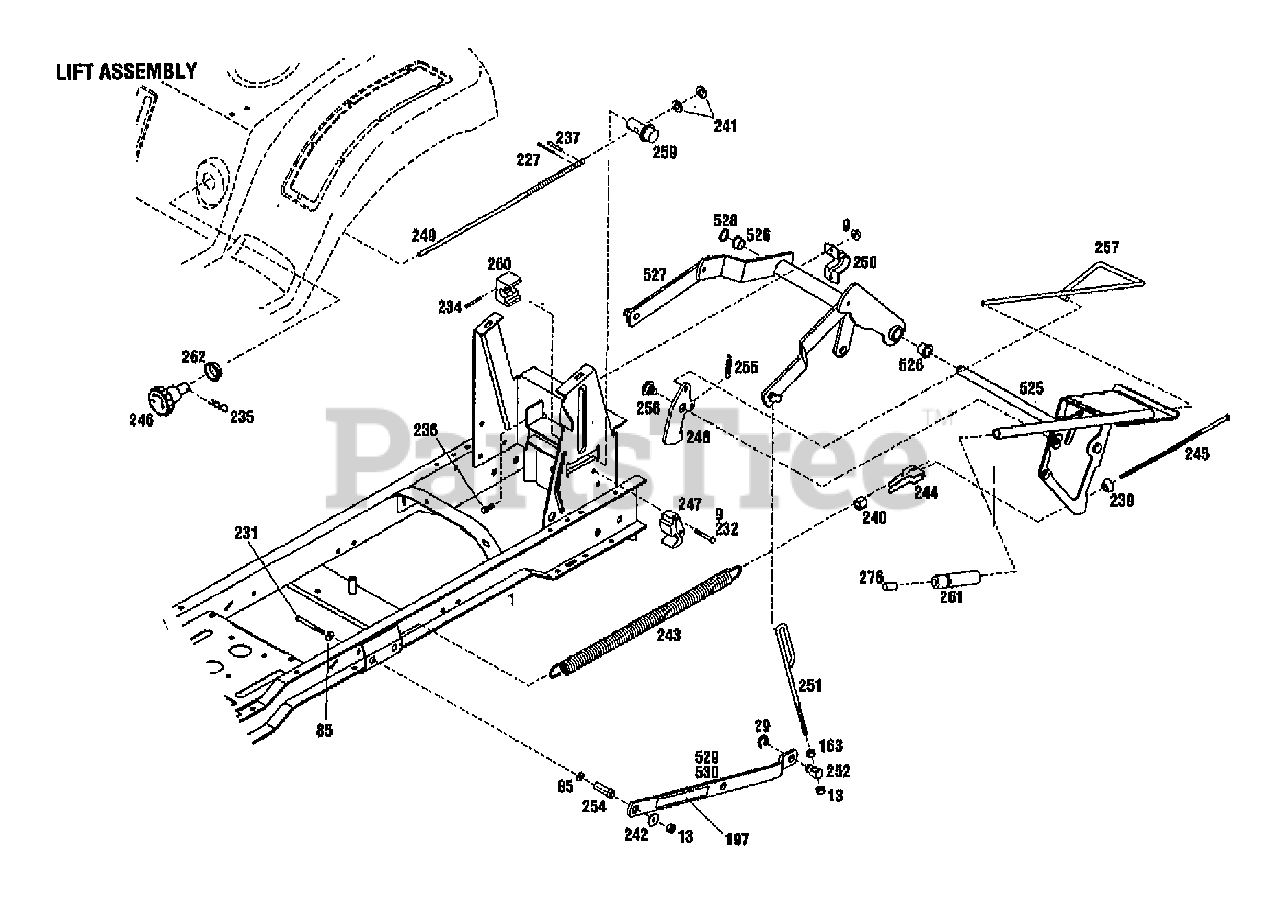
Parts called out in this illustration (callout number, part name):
9	NUT-HFLK 5/16-18 ZP
13	NUT-LOCK 3/8-16
29	RING-RETAINING
85	WASHER-FLAT 3/8 SAE
163	NUT-HEX 3/8-16 ZP
197	DECAL-WARNING
227	PIN-COTTER .125 X .75 ZP
231	SCR-HH 3/8-16X3.0 G5 ZP
232	SCR-HH 5/16-18X1.5 G5 ZP
234	PIN-DRIVE {13097}
235	PIN-HITCH {13097}
236	SCR-HFLK 5/16-18X.75 ZP
237	PIN-ROLL .156X1.0 {13097}
239	BEARING-SPHERICAL
240	NUT-SPECIAL 5/16-18
241	SPACER {13097}
242	WASHER-1.5X.375X.18 ZP
243	SPRING-LIFT ASSIST
244	BRKT-LIFT ASSIST
245	SCR-LIFT ASSIST
246	KNOB-HEIGHT ADJUST {13097}
247	BLOCK-DETENT
249	KIT-SVC SCR HGT ADJ {13097}
250	CLAMP-LIFT
252	SWIVEL-REAR LIFT
254	SPACER
255	SPRING-EXTENSION
256	SCR-SHOULDER
259	BLOCK-HEIGHT ADJUST {13097}
260	COLLAR-HEIGHT ADJUST {13097}
261	GRIP-LIFT
262	GROMMET-SNAP BUSHING {13097}
276	BUTTON-LIFT
525	HANDLE-LIFT
528	RING-RETAINING EXT .694 ID
529	LINK-LIFT W/DECAL
530	LINK-LIFT W/DECAL
